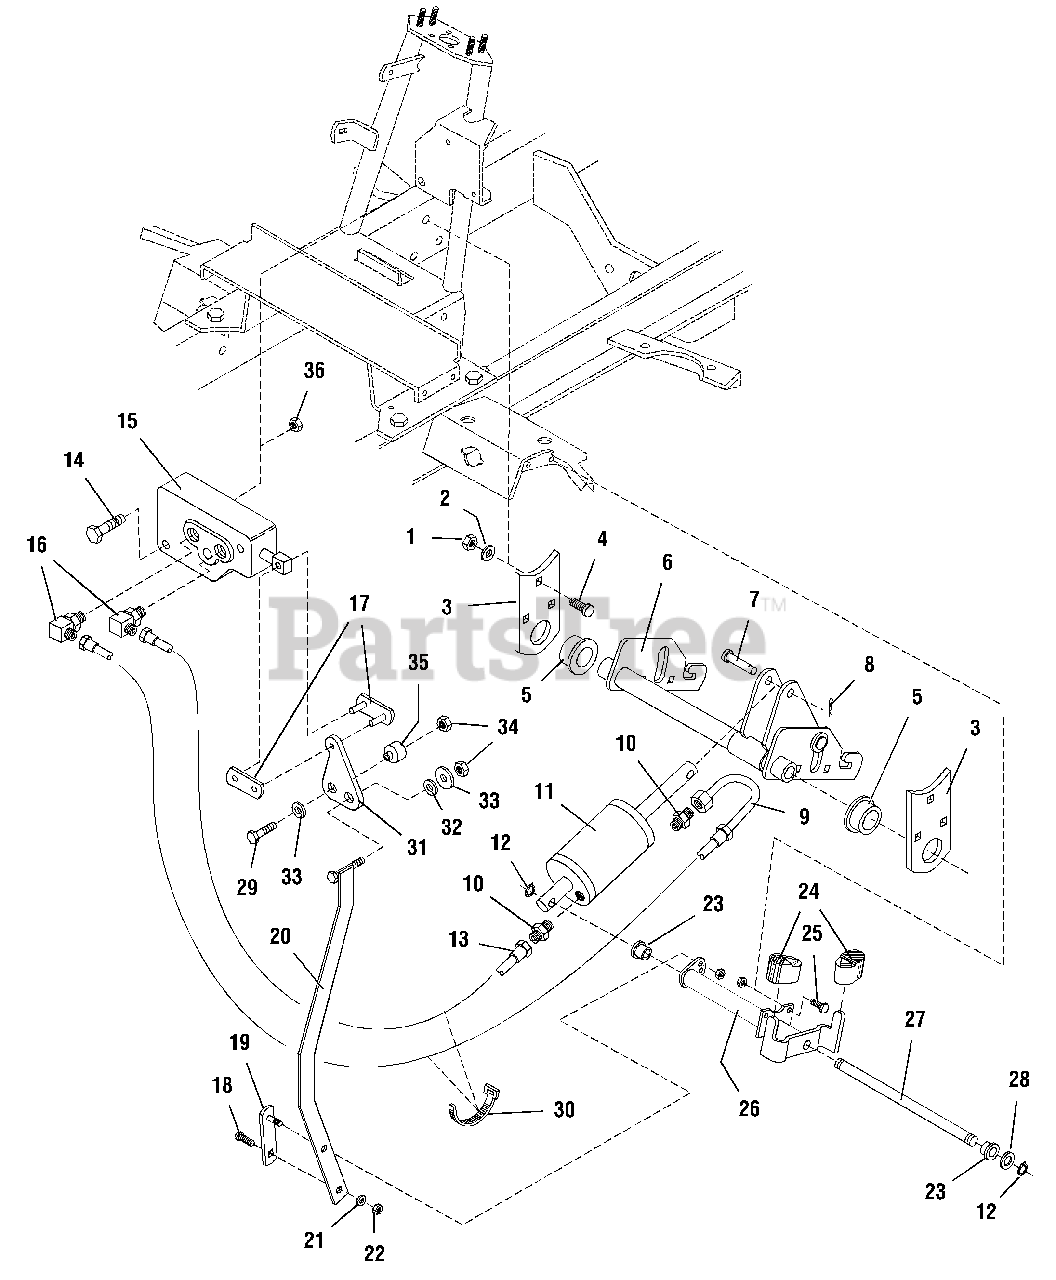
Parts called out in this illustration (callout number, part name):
1	NUT, Hex, Full, 3/8-16
2	LOCKWASHER, 3/8
3	PLATE, Bearing
4	CARRIAGE BOLT, 3/8-16 x 1
5	BUSHING, Lift
6	SHAFT ASSEMBLY, Lift
7	PIN, Clevis
8	PIN, Cotter, 1/8 x 1
9	HOSE, Valve to Cylinder (UP)
10	FITTING, Male, Straight
11	CYLINDER, Hydraulic Lift
12	KLIPRING, 1/2
13	HOSE, Valve to Cylinder (Down)
14	CAPSCREW, Hex Hd, 1/4-20 x 2
15	VALVE ASSY, Lift
16	FITTING, 90°.
17	LINK, Connecting
18	CARRIAGE BOLT, 1/4-20 x 3/4
19	LINK ASSEMBLY, Lower
20	LINK ASSY, Upper
21	WASHER, Plain, 1/4
22	NUT, Hex, Nylon Lock, 1/4-20
23	BUSHING, Nylon
24	PAD, Foot Pedal
25	CAPSCREW, Hex Hd, 1/4-20 x 3/4
26	PEDAL ASSEMBLY, Hydraulic Lift
27	SHAFT, Pivot
28	WASHER, Flat, 1/2 x 7/8
29	CAPSCREW, Hex Hd, 5/16-18 x 1-1/2
31	PIVOT, Valve
33	WASHER, Flat, 5/16
34	NUT, Hex, Nylon Lock, 5/16-18
36	NUT, Hex ,Whizlock, 1/4-20
